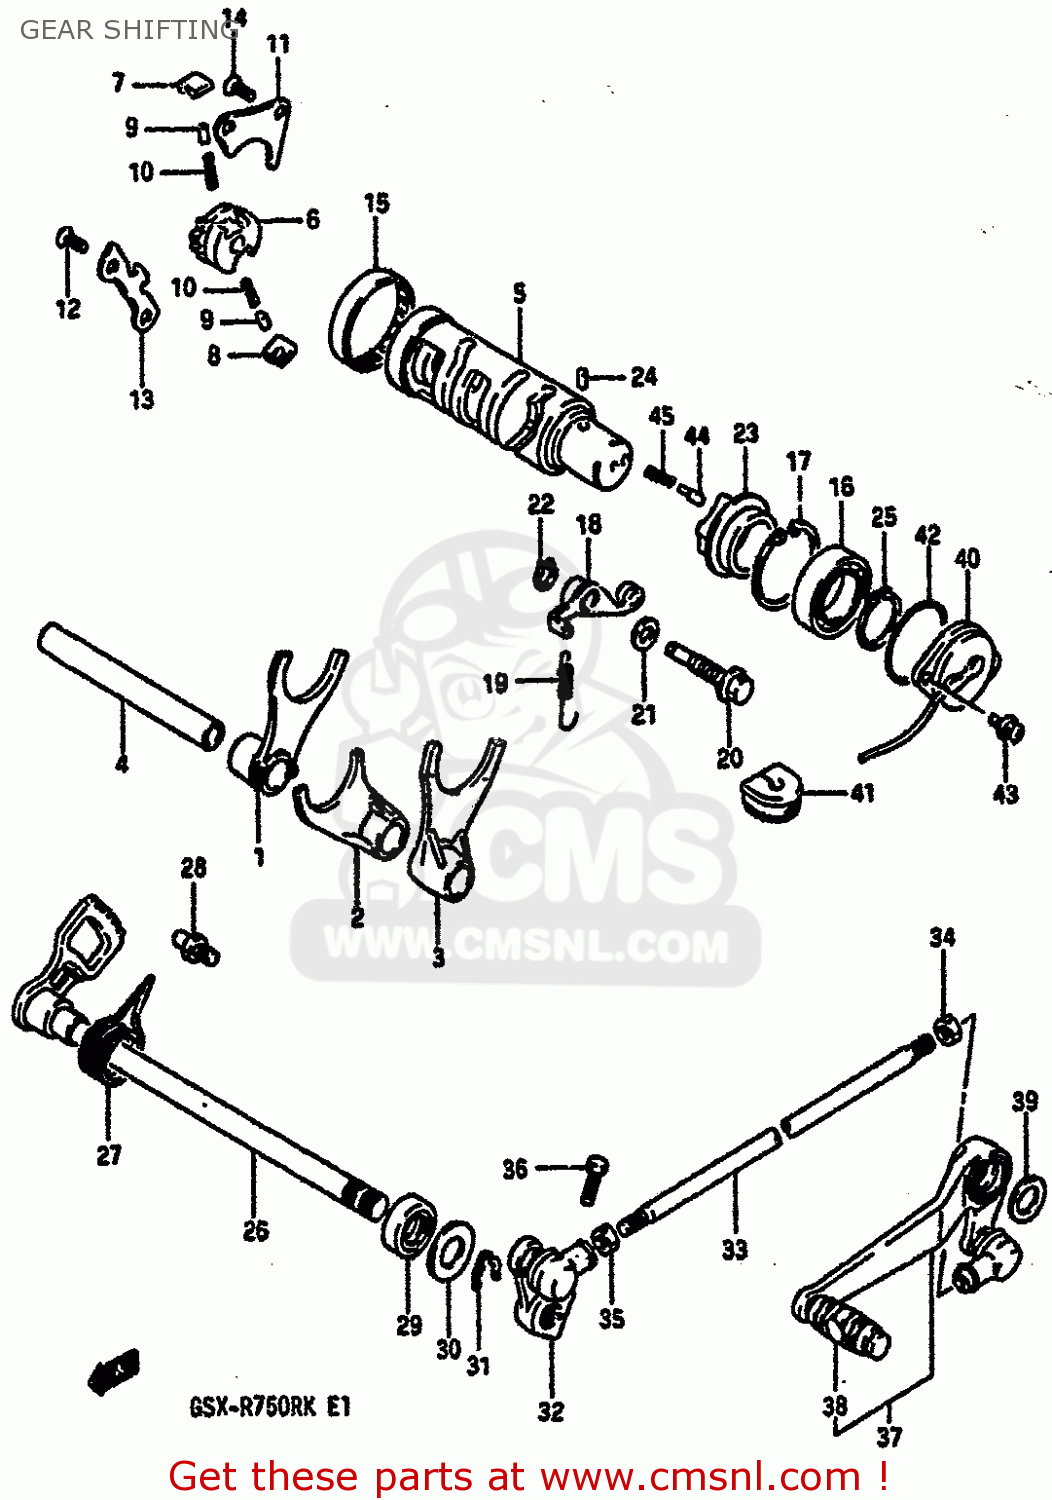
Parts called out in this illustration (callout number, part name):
1	FORK,GEAR SHIFT NO.1
2	FORK,GEAR SHIFT NO.2
3	FORK,GEAR SHIFT NO.3
4	SHAFT,GEAR SHIFT FORK(L:128)
5	CAM,GEAR SHIFT
6	GEAR,GEARSHIFT CAM DRIVE
7	PAWL,GEAR SHIFT NO.1
8	PAWL,GEAR SHIFT NO.2
9	PIN(5X8)
10	SPRING
11	LIFTER,GEAR SHIFT PAWL
12	SCREW
13	GUIDE,GEAR SHIFT CAM
14	SCREW
15	BEARING(43X49X12)
16	BALL BEARING
17	CIRCLIP,42MM
18	STOPPER,GEAR SHIFT CAM
19	SPRING
20	SHAFT,GEAR SHIFT CAM STOPPER
21	GASKET(10X14X3.6) (NAS)
22	CIRCLIP
23	PLATE,STOPPER
24	PIN 4X6
25	CIRCLIP,25MM
26	SHAFT,GEAR SHIFT
27	SPRING
28	STOPPER,GEAR SHIFT CAM
29	OIL SEAL
30	WASHER (12.5X27X1.6)
31	SPRING,RETAINER
32	ARM,GEAR SHIFT
33	ROD,GEAR SHIFT LINK
34	NUT
35	NUT 6MM
36	BOLT
37	LEVER ASSEMBLY,GEAR SHIFTING
38	RUBBER,GEAR SHIFT PEDAL
39	WASHER(18X24X1)
40	TERMINAL BASE ASSY,NEUTRAL
41	GROMMET,LEADWIRE
42	O RING(D:2.4,ID:36.5)
43	SCREW
44	PIN(5X15.5)
45	SPRING
